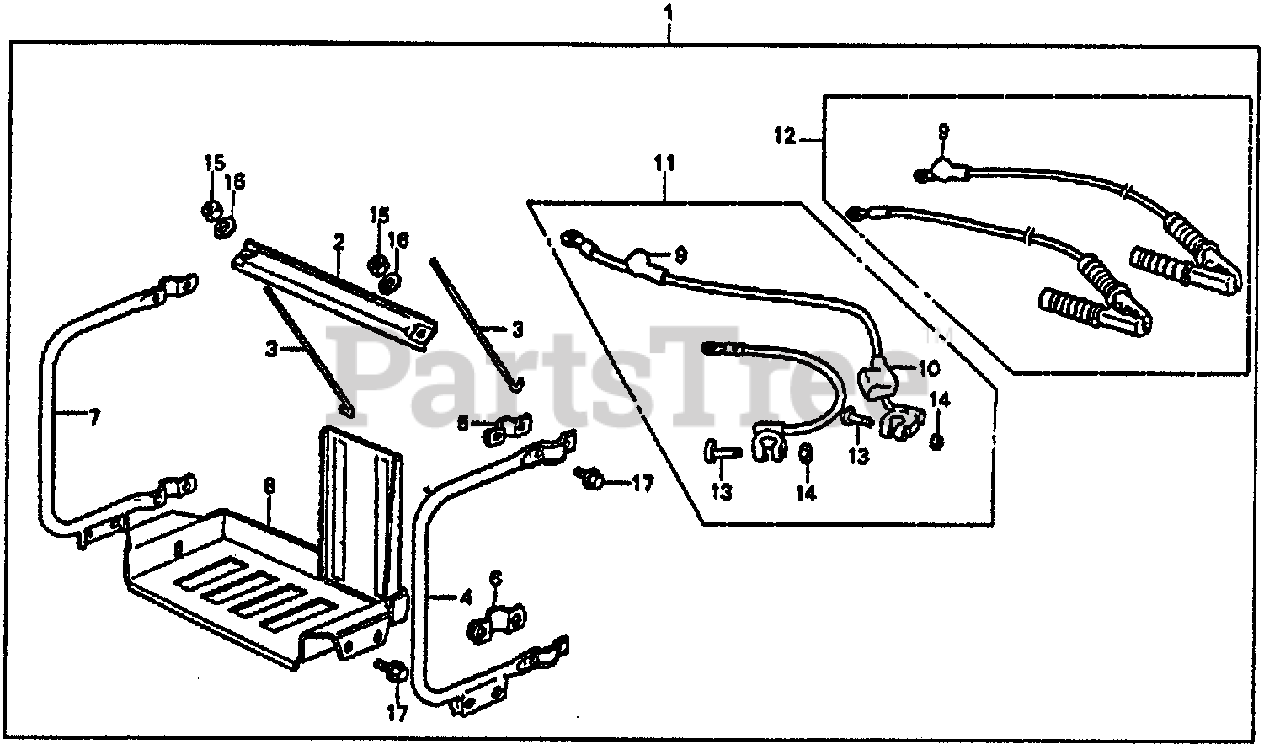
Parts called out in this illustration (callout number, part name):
1	TRAY KIT, BATTERY (NOT AVAILABLE)
2	PLATE, BATTERY SETTING
3	BOLT, BATTERY SETTING (220MM)
4	PIPE, FR. BATTERY GUARD
5	PLATE A, SETTING
6	PLATE B, SETTING
7	PIPE, RR. BATTERY GUARD
8	CASE, BATTERY (NOT AVAILABLE)
9	COVER, TERMINAL
10	COVER, BATTERY PLUS TERMINAL (SOURCE: VINTAGE PARTS INC.)
11	CABLE ASSY., STARTING
12	WIRE ASSY., BATTERY
12	WIRE ASSY., BATTERY (NOT AVAILABLE)
13	BOLT (6X32) (NOT AVAILABLE)
14	NUT (6MM) (SOURCE: VINTAGE PARTS INC.)
15	NUT, HEX. (6MM)
16	WASHER, PLAIN (6MM)
17	BOLT, FLANGE (6X12)
